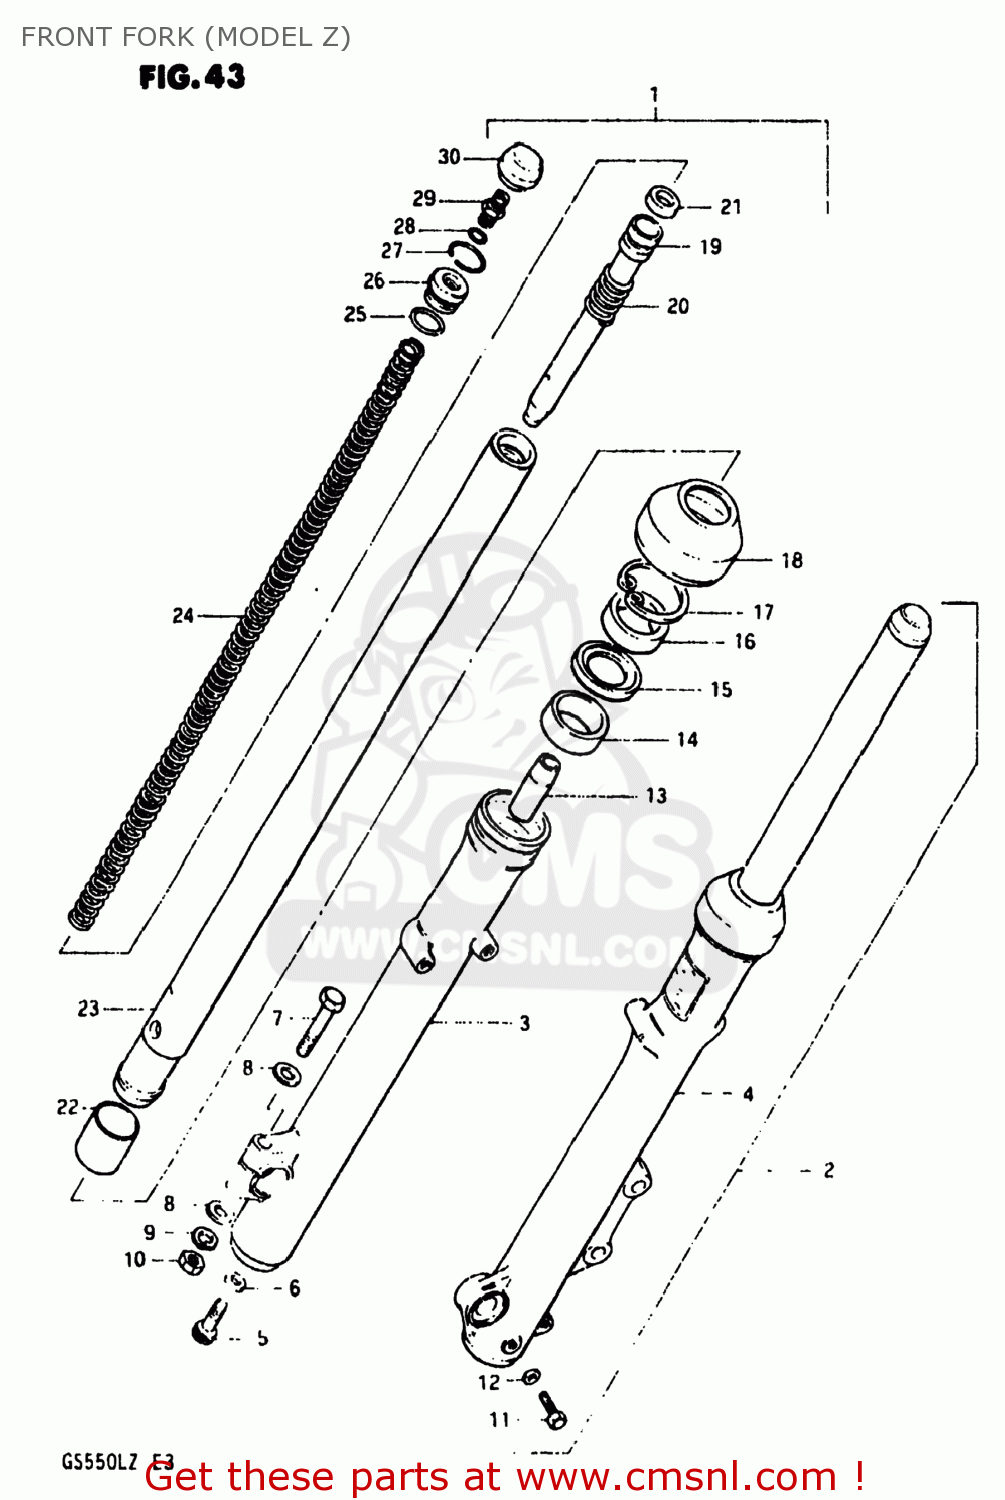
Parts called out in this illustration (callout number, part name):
1	DAMPER ASSEMBLY,RIGHT
2	DAMPER ASSEMBLY,FRONT FORK,LEFT
3	TUBE,FORK,OUTER,RIGHT
4	TUBE,OUTER,LEFT
5	BOLT(8X27)
6	GASKET (NAS)
7	BOLT 8X50
8	WASHER
9	LOCK WASHER
10	NUT
11	BOLT
12	GASKET,DRAIN,PLUG (NAS)
13	PIECE,OIL LOCK
14	BUSH,GUIDE
15	SPACER,SEAL
16	OIL SEAL,FRONT FORK
17	CIRCLIP,FORK OIL SEAL
18	BOOT
19	CYLINDER,FRONT FORK
20	SPRING,FORK REBOUND
21	RING
22	PISTON
23	TUBE,FORK,INNER
24	SPRING,FRONT
25	O-RING
26	SEAT,SPRING
27	RING,STOPPER
28	O-RING
29	VALVE,AIR
30	CAP
